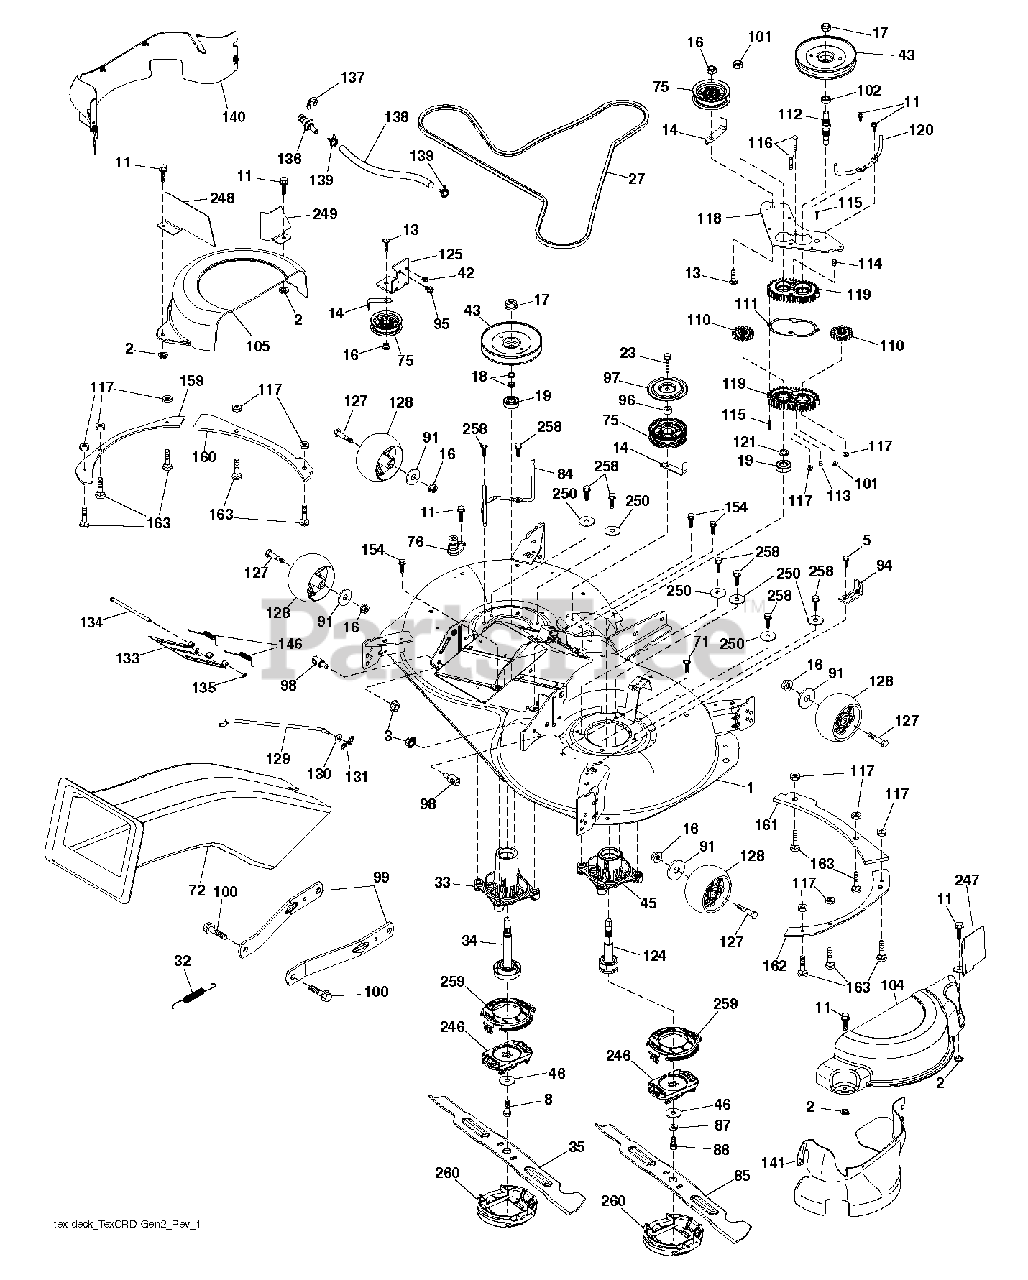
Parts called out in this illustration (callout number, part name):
1	DECK SVC 107HP.EZMUL.498
2	PALNUT 1/4
3	NUT LOCK HEX FLANGE 5/16-18
5	BOLT.5/16HEX.WHS.HD
8	SCREW.SEMS.7/16-20X1.HEX.HEAD
11	SCREW.1/4-20X5/8
13	BOLT.3/8-16X1.50
14	KEEPER, BELT IDLER
16	NUT LOCK FLG 3/8-16 UNC
17	NUT.FLANGE.LOCK.TOP
18	WASHER.SPACER.MANDREL
23	SCREW LT
27	BELT BELT. ELECTRIC MOWER DRIV
32	SPRING 107CM & 97CM ELECTRIC D
33	HOUSING.MANDREL.REV.TALL.N/GRS
34	SHAFT ASM.REV.TALL.N/GREASEBL
35	BLADE.107.LH.SINGLE.NON.QD
42	SCREW
43	PULLEY PULLEY MANDREL 5.438 PD
45	RP HOUSING.MANDREL.REV.REVS.
46	3/8 FLAT WASHER
71	SCREW 3/8-16X1/2
72	CHUTE.107/97.TEX.GEN2.TRIMMED
75	FLAT IDLER PULLEY
76	1/2" BARB.DECK.WASHOUT.PORT
84	KEEPER KEEPER. LH MANDREL BELT
85	BLADE.107.RH.SINGLE.NON.QD
86	BOLT.3/8-24X1.25GR8. LHTHRD
87	LOCKWASHER
91	WASHER
94	BRKT.CLUTCH.CABLE
95	SCREW, 3/8-16X3/4
96	SPACER
97	PROTECTOR
98	STUD.FASTNER.W/ANTI-ROTATE
99	ARM.SUSPENSION.MOWER.R
100	BOLT.SHOULDER
101	NUT.CROWNLOCK.9/16 -18.UNC
102	SPACER BEARING
104	COVER.MANDREL.107.RH.GEN.2
105	COVER.MANDREL.107.LH.GEN.2
110	GEAR GEAR OUTPUT
111	GASKET GASKET GEARCASE
112	SHAFT SHAFT. CRD GEARCASE ADAP
113	PLUG PLUG OIL
114	VALVE VALVE RELIEF
115	SCREW
116	BOLT.CARIGE.SS.1/4-20X1.75GR5
117	NUT T
118	ARM ARM. CLUTCHING 107 TEX CRD
119	GEARCASE GEARCASE SUBASM
120	KEEPER KEEPER. RH MANDREL BELT
121	WASHER WASHER
124	SUB.ASM.REVERSE.THREAD.REV
125	BRACKET
127	BOLT.SHOULDER.3/8-16X3-5/8.
128	WHEEL. GUAGE RALLY
129	ROD ROD. SWAY CRD GEN II
130	WASHER
131	PIN.COTTER.5/16.BOW TI
133	COVER DOOR.107 CM CRD EZ MULCH
134	PIN PIN.HINGE
135	E-RING.5/16"
136	PLUG WASHOUT PORT HOOKUP
138	107.WASHOUT.PORT.HOSE (2 2)
139	HOSE.3/8.CLAMP (2 2)
140	GUARD FRENCH 107 TEX ASSEMBLY
141	GUARD SUBASM. 107 TEX GEN 2 RH
146	SPRING SPRING: EZ MULCH DOOR
154	SCREW T-30 1/4-20 X
159	PLATE.107CRD.LH.SIDE.BLTON
160	PLATE.107CRD.LH.FRONT.BOLT-ON
161	PLATE.107CRD.RH.FRONT.BOLT-ON
162	PLATE.107CRD.RH.SIDE.BOLT-ON
163	BOLT
246	HOLDER BLADE REVOLUTION
247	GUARD.STEEL.CRD.MANDREL.COV.FR
248	GUARD.STEEL.CRD.MANDREL.COV.FR
249	GUARD.STEEL.CRD.MANDREL.COV.FR
258	BOLT.HEX.WASHR.HED.313-18X1.19
259	CAP.REVOLUTION.UPPER
260	CAP.REVOLUTION.LOWER
